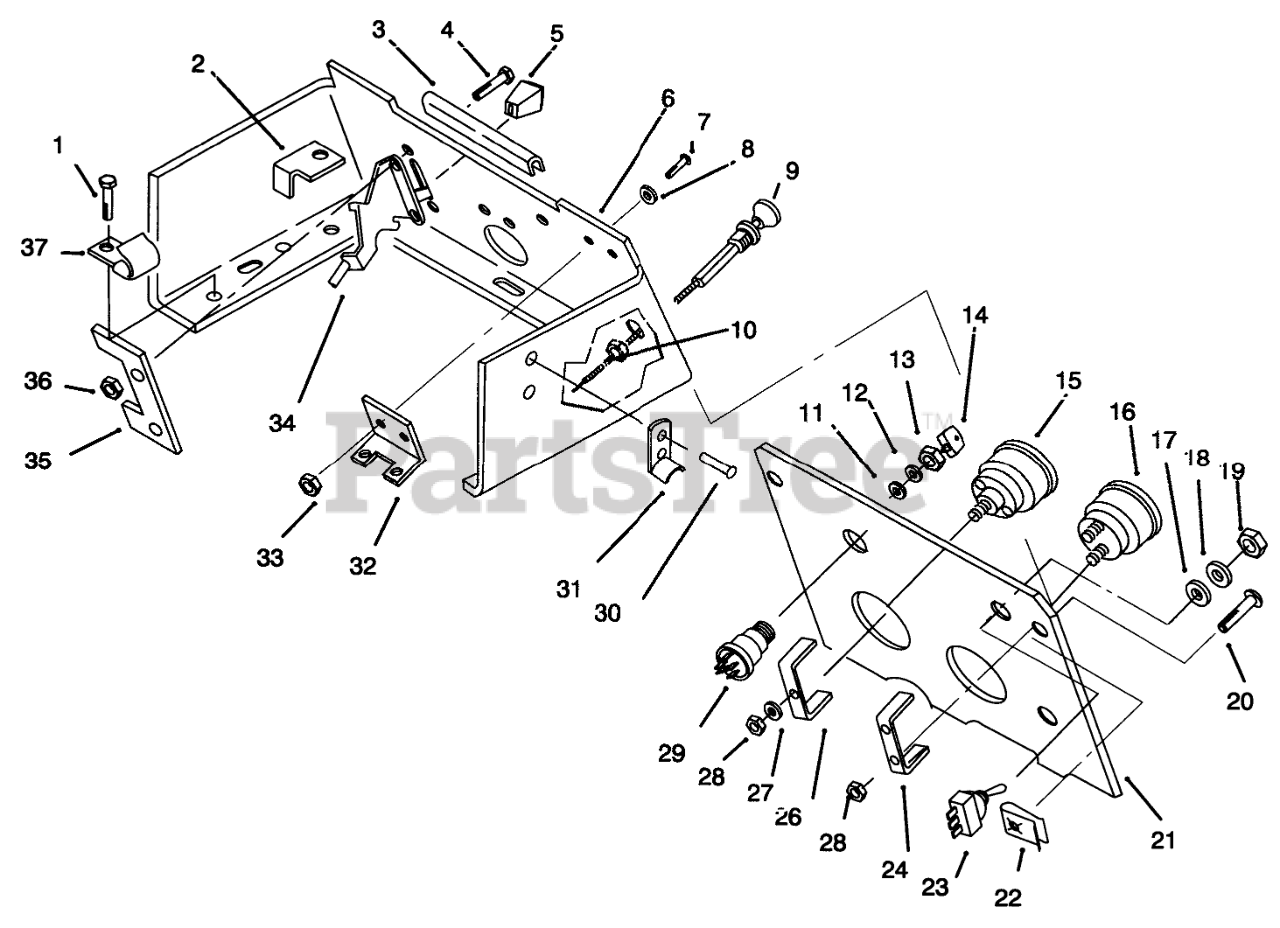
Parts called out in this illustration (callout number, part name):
1	Bolt
2	STOP-PTO
3	EDGING-CONSOLE
4	Screw
6	Console
7	SCREW-PAN
8	Washer-Lock
9	CONTROL-CHOKE
11	WASHER
12	WASHER-LOCK
14	KEY-IGNITION
15	Meter-Hour (Incl. Ref. #27-28)
16	Meter-Volt (Incl. Ref. #24-25)
17	Washer
18	TAB-WASHER
20	SCREW-PPH
21	Plate-Hood Stand
22	CLIP
23	Switch-Light (Incl. Ref. #17-19)
24	CLAMP-MOUNTING
26	CLAMP-HOUR METER
27	WASHER-LOCK
28	NUT-HEX
29	Switch-Ignition (Incl. Ref. #11-13)
30	POPRIVET 1/8X 1/8 BK
31	KEEPER-LATCH
32	BRACKET
33	Nut
34	CONTROL-THROTTLE
35	Washer
36	Nut
37	J-CLIP
